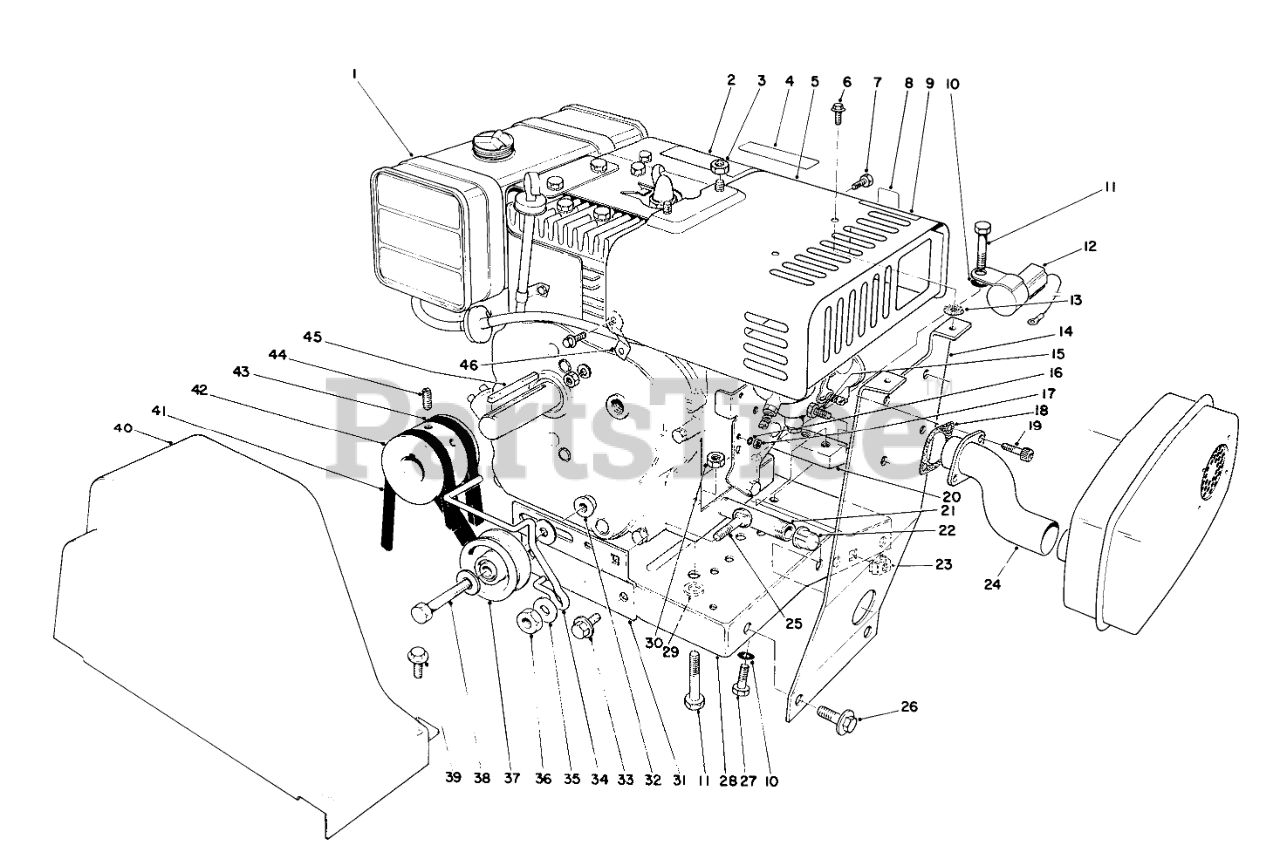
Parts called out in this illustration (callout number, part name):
1	Engine
2	CAUTION DECAL
3	NUT-HEX, SIDE DEFORM
4	DECAL SYNCHRO BALANCE
5	Heater Box
6	SCREW-HWH
8	CHOKE DECAL
9	HOT SURFACE DECAL
10	WASHER-LOCK, INTERNAL
11	SCREW-HH
12	INTERLOCK MODULE
13	Washer
14	Muffler Mounting Bracket
15	1/4-20 X 1/2 SEMS MS
16	WASHER-LOCK/INT
17	NUT-LOCK
18	Gasket
19	SCREW-HSH
20	Block Engine Mounting
21	NIPPLE-PIPE
22	CAP-PIPE
23	RETAINER NUT
24	EXHAUST PIPE
25	SCREW-CARR
26	SCREW-HH
27	SCREW-HH
28	Base-Engine
29	WASHER-PLAIN
30	NUT-LOCK, NI
31	BELT IDLER BRKT
32	NUT-HHF, WHIZ
33	SCREW-HHFTF
34	BELT GUIDE
35	WASHER-FLAT
36	NUT-LOCK, NI
37	PULLEY B
38	SCREW-HH
39	SCREW-HWH
40	BELT GUARD
41	V-BELT
42	ENGINE PULLEY
43	V-BELT
44	Screw-Set
46	Brace Heater Box
